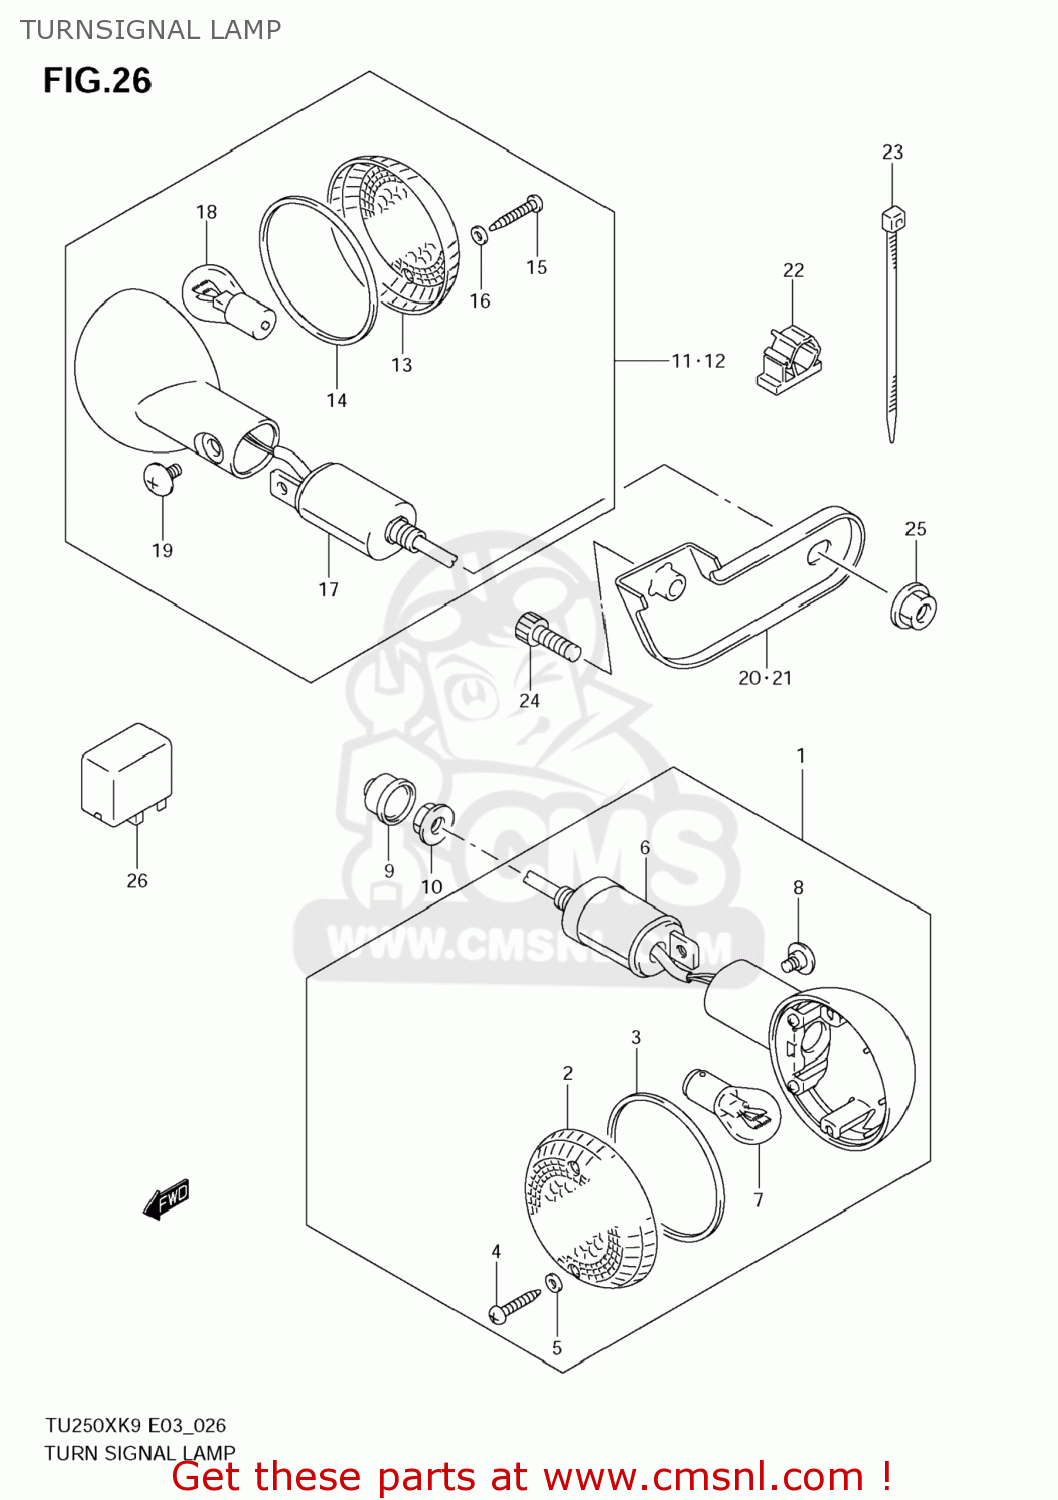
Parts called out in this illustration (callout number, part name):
1	LAMP ASSY,FR TURN SIGNAL
2	LENS
3	GASKET (NAS)
4	SCREW
5	GASKET (NAS)
6	STAY,TURNSIGNAL FR
7	BULB(12V21W)
8	SCREW
9	COVER,TURNSIGNAL
10	NUT
11	LAMP ASSY,RR TURNSIGNAL,R
12	LAMP ASSY,RR TURNSIGNAL,L
13	LENS
14	GASKET (NAS)
15	SCREW
16	GASKET (NAS)
17	STAY,TURNSIGNAL FR
18	BULB(12V21W)
19	SCREW
20	BRACKET,RR TURNSIGNAL,R
21	BRACKET,RR TURNSIGNAL,L
22	CLAMP
23	CLAMP(L:145)
24	BOLT
25	NUT
26	RELAY ASSY,TURNSIGNAL LAMP
